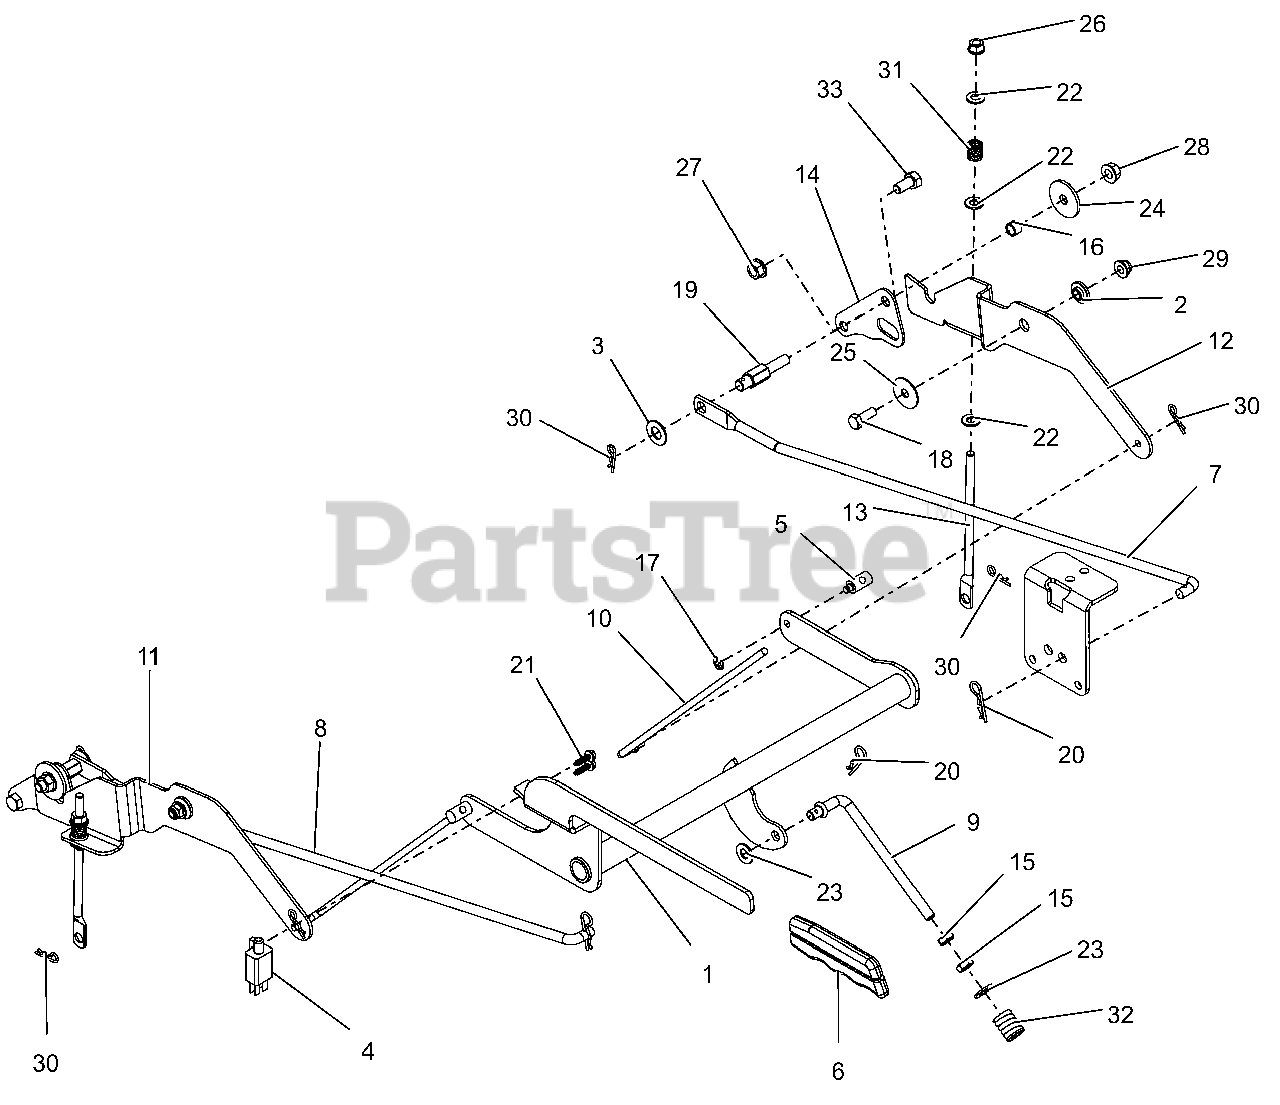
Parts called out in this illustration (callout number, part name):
1	WLDMT, BRAKE LEVER
2	BSHG, FLG .325X.499X.26X.88
3	WSHR, FLT .505X1.00X.062 ZCC
4	SWITCH- DOUBLE POLE N.O./N.O.
5	TRUNION, 1/4-20
6	GRIP, PARKING BRAKE (YELLOW)
7	ROD, STEERING LINKAGE LH
8	LINKAGE, STEERING - RH
9	LINK, OVER CENTER, PARKING BRK
10	ROD, PARK BRAKE
11	INTERLOCK, RH BRAKE LINK
12	INTERLOCK, LH BRAKE LINK
13	LINK, TRANSAXLE BRAKE
14	PLATE, TRANSAXLE ADAPTOR
15	NUT-JAM .375-16 G2 ZCC
16	SPCR, SLV .385X.500X.350
17	RG-RTNG-EXT .250X.025
18	BLT, HEX .31-18X.875 G5 ZCC
19	POST, STEERING LINK MOUNTING
20	PIN, HAIR .09 X 1.50 ZCC
21	SCR, PLASTITE-HWH 0.2 X 0.75 ZC120
22	WSHR,FLT .344X.688X.065 ZCC
23	WSHR,FLT .406X.812X.065 ZCC
24	WSHR, FLT .380X1.50X.125 ZCC
25	WSHR, FLT .347X1.254X.048 ZCC
26	NUT,LK-CTR-FLG .31-18 GF ZCC
27	NUT-LK-CTR-FLG .375-16 GF ZCC
28	NUT-LK-CTR-FLG .375-16 GF ZCC
29	NUT,NYL-FLG .31-18 GF ZCC
30	PIN, HAIR #213 .08X1.19 ZCC
31	SPRING, COMPRESSION
32	SG-COMP .187X.56X1.62
33	BLT,HEX .38-16X.75 G5 ZCC
